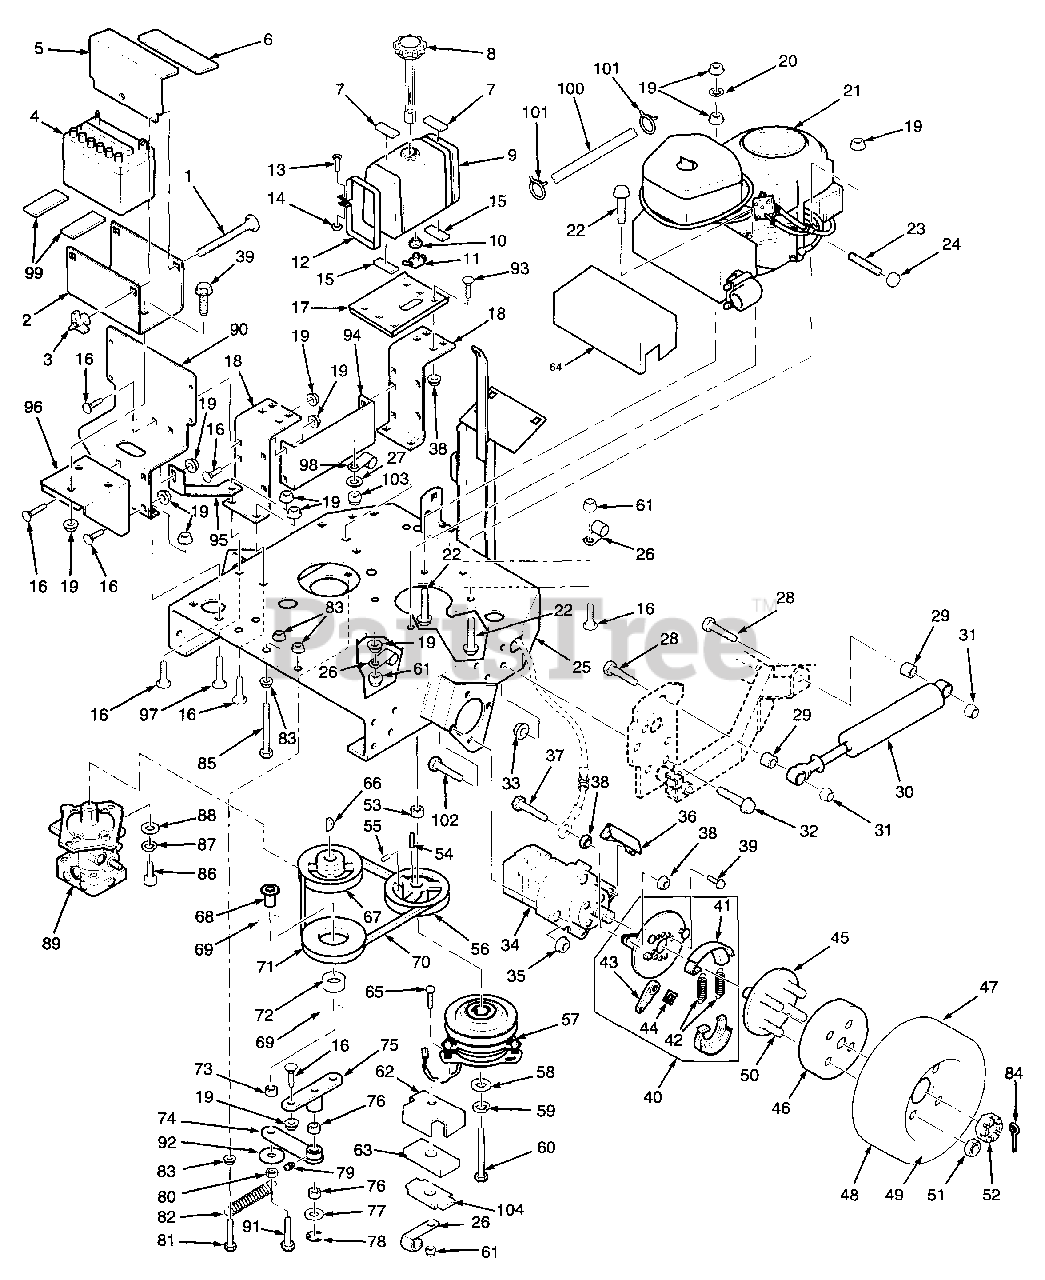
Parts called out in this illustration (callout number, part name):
1	Carriage Bolt, 1/4-20 x 6"
2	Battery Box
3	Nut, Wing 1/4-20
4	Battery
5	Battery Cover
6	insulation, Battery Cover
7	Pad, Fuel Tank Strap
8	Cap, Fuel Tank
9	Fuel Tank Assy.
10	Bushing, Fuel Tank Valve
11	Fuel Shut Off Valve
12	Strap, Fuel Tank
13	Phil RDHD Machine Screw 1/4-20 x 2"
14	Hex Nut, 1/4-20
15	Pad, Fuel Tank Support
16	Carriage Bolt, 5/16-18 x 3/4"
17	Support, Fuel Tank
18	Bracket, Fuel Tank Support
19	Serr. Fl. Hex Nut 5/16-18
20	Lockwasher, 5/16 Int. Tooth
21	Engine, 22 HP Kohler CV, (Spec PS-75515)
22	Hex Head CPSCR, 5/16-18 x 1-3/4"
23	Oil Drain Extension
24	Cap, Oil Drain Plug
25	Engine Deck
26	Wire Loom, .50 I.D.
27	Washer, 1/4 (.312 x .750 x .065)
28	Bolt, Hex Head 1/2-13 x 2"
29	Sleeve, Shock Absorber Mount
30	Shock Absorber
31	Hex Locknut, Elastic Stop 1/2-13
32	Serr. Fl. Hex Head CPSCR, 7/16-14 x 1"
33	Serr. Fl. Hex Nut, 7/16-14
34	Motor - White
35	Lockwasher, 1/2"
36	Anchor, Brake
37	Bolt, Hex Head 1/4-20 x 1-1/4"
38	Serr. Fl. Hex Nut, 1/4-20
39	Serr. Fl. Hex Head CPSCR, 5/16-18 x .75"
40	Parking Brake Assembly
41	Brake Pads- Pair
42	Springs - Pair
43	Actuating Arm
45	Hub Assembly
46	Brake Drum
47	Rim and Tire Assembly
48	Tire 20 x 10 x 10, 4 Ply
49	Rim Only
50	Bolt, Hub
51	Wheel Nut
52	Castle Nut, 1.0-20 UNEF
53	Spacer, Clutch
54	Key, 1/4 x 1/4 x 1-1/2"
55	Hex Socket Set Screw, 5/16-18 x 3/8"
56	Pulley, Engine Pump Drive
57	Clutch, Electric (Ogura)
58	Flatwasher, 7/16 (.469 x 1.75 x .25)
59	Lockwasher, 7/16"
60	Bolt, Hex Head 7/16-20 x 2.75"
61	Hex Locknut, Elastic Stop 5/16-18
62	Backing Plate, Clutch Stop
63	Rubber Pad, Clutch Stop
64	Heatshield, Muffler
65	Bolt, Hex Head 5/16-18 x 1-3/4"
66	Key, Woodruff 3/16 x 5/8"
67	Pulley, Pump Input
68	Sleeve, Idler
69	Ring, Retaining, 1-9/16 Internal
70	Belt, Pump Drive
71	Pulley, Idler-Traction Drive
72	Bearing, Idler Pulley
73	Spacer, idler
74	Pump Idler Arm
75	Idler Pivot Base
76	Bushing, Oillube
77	Flatwasher, 3/4"
78	Ring, Retaining, 3/4" Ext. "E"
79	Grease Fitting
80	Hex Nut, Jam 3/8-16
81	Bolt, Hex Head 3/8-16 x 3-1/4"
82	Spring, Pump Drive Idler
83	Serr. Fl. Hex Nut, 3/8-16
84	Cotter Pin, 5/32 x 1.50"
85	Bolt, Hex Head 3/8-16 x 5"
86	Socket Head CPSCR, 1/2-13 x 1-1/4"
87	Lockwasher, 1/2"
88	Flatwasher, 1/2 (.5/6 x .938 x .105)
89	Pump, Sundstrand
90	Bracket, Oil Tank Support
91	Bolt, Hex Head 3/8-16 x 1-3/4"
92	Washer 2" OD, 3/8 ID, 16 Ga.
93	Carriage Bolt, 1/4-20 x 3/4"
94	Guard, Pulley
95	Gusset, Battery Box
96	Support, Battery Box
97	Carriage Bolt, 5/16-18 x 1"
98	Wire Loom, .75" I.D.
99	Rubber Pad
100	Fuel Hose
101	Clamp, Fuel Hose
102	Bolt, 1/2-13 x 2.50"
103	Nut, 1/4-20 Elastic Stop
104	Plate, Backing
